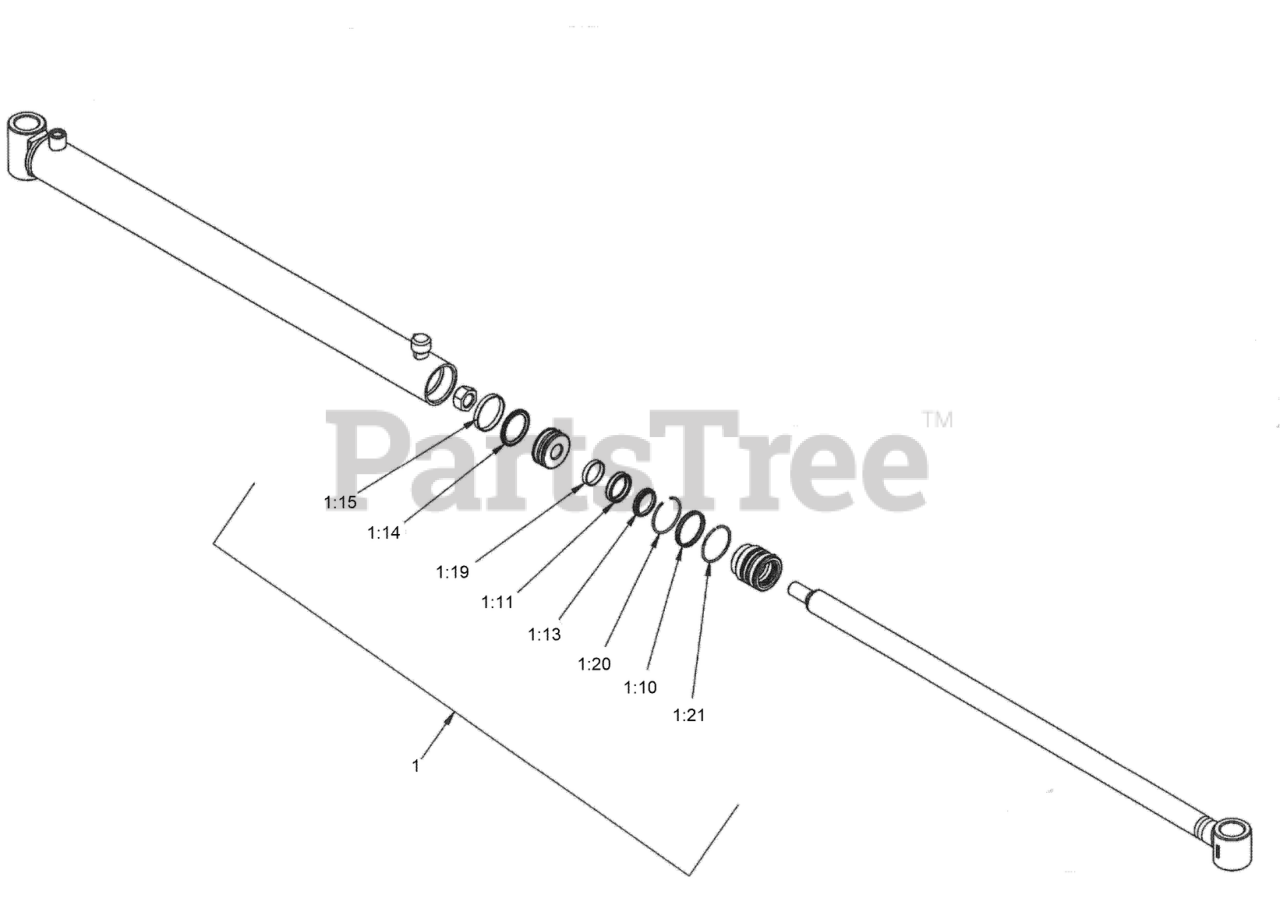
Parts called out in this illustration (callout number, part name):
1	KIT-SEAL, HYDRAULIC CYL
1:10	SEAL-DUAL
1:11	SEAL-ROD
1:13	Rod Wiper
1:14	Seal-Piston
1:15	PISTON WEAR RING
1:19	ROD WEAR RING
1:20	INTERNAL RETAINING RING
1:21	EXTERNAL RETAINING RING
